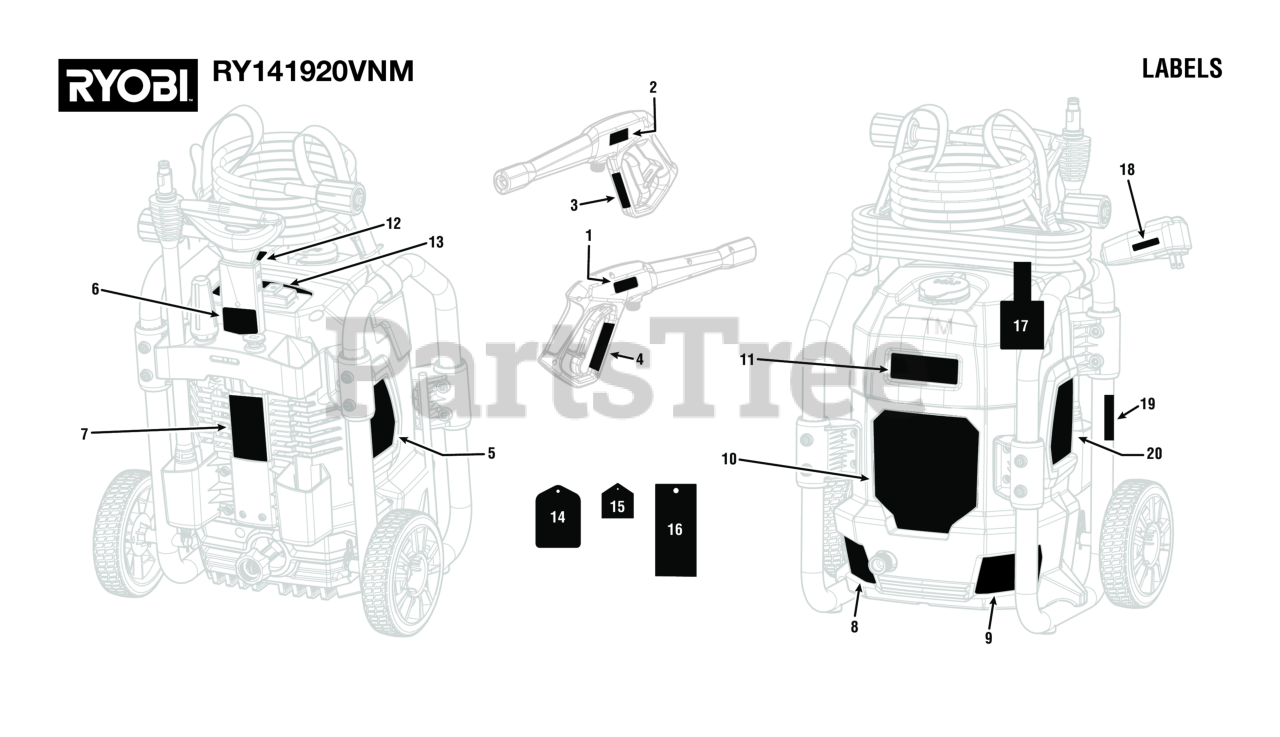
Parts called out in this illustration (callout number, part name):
1	Trigger Handle Label (Logo Label)
2	Trigger Handle Warning Label (English)
3	Trigger Handle Data Label
4	Trigger Handle Warning Label (French/Spanish)
5	Icons/FR Warnings Label
6	Soap Instructions Label
7	Data Label
8	Right Side Vent Label
9	Left Side Vent Label
10	Performance Label
11	Logo Label
12	Detergent Tank Label
13	Starting Instructions and On/Off Label
14	Nozzle Hangtag (PS141913)
15	Hang Tag, Echo Prop 65
16	Danger Hangtag (Spanish)
17	Warning Label (Cord Wrap)
18	Power Cord Label
19	Inquires Label (Ryobi)
20	Icons/EN Warnings Label
